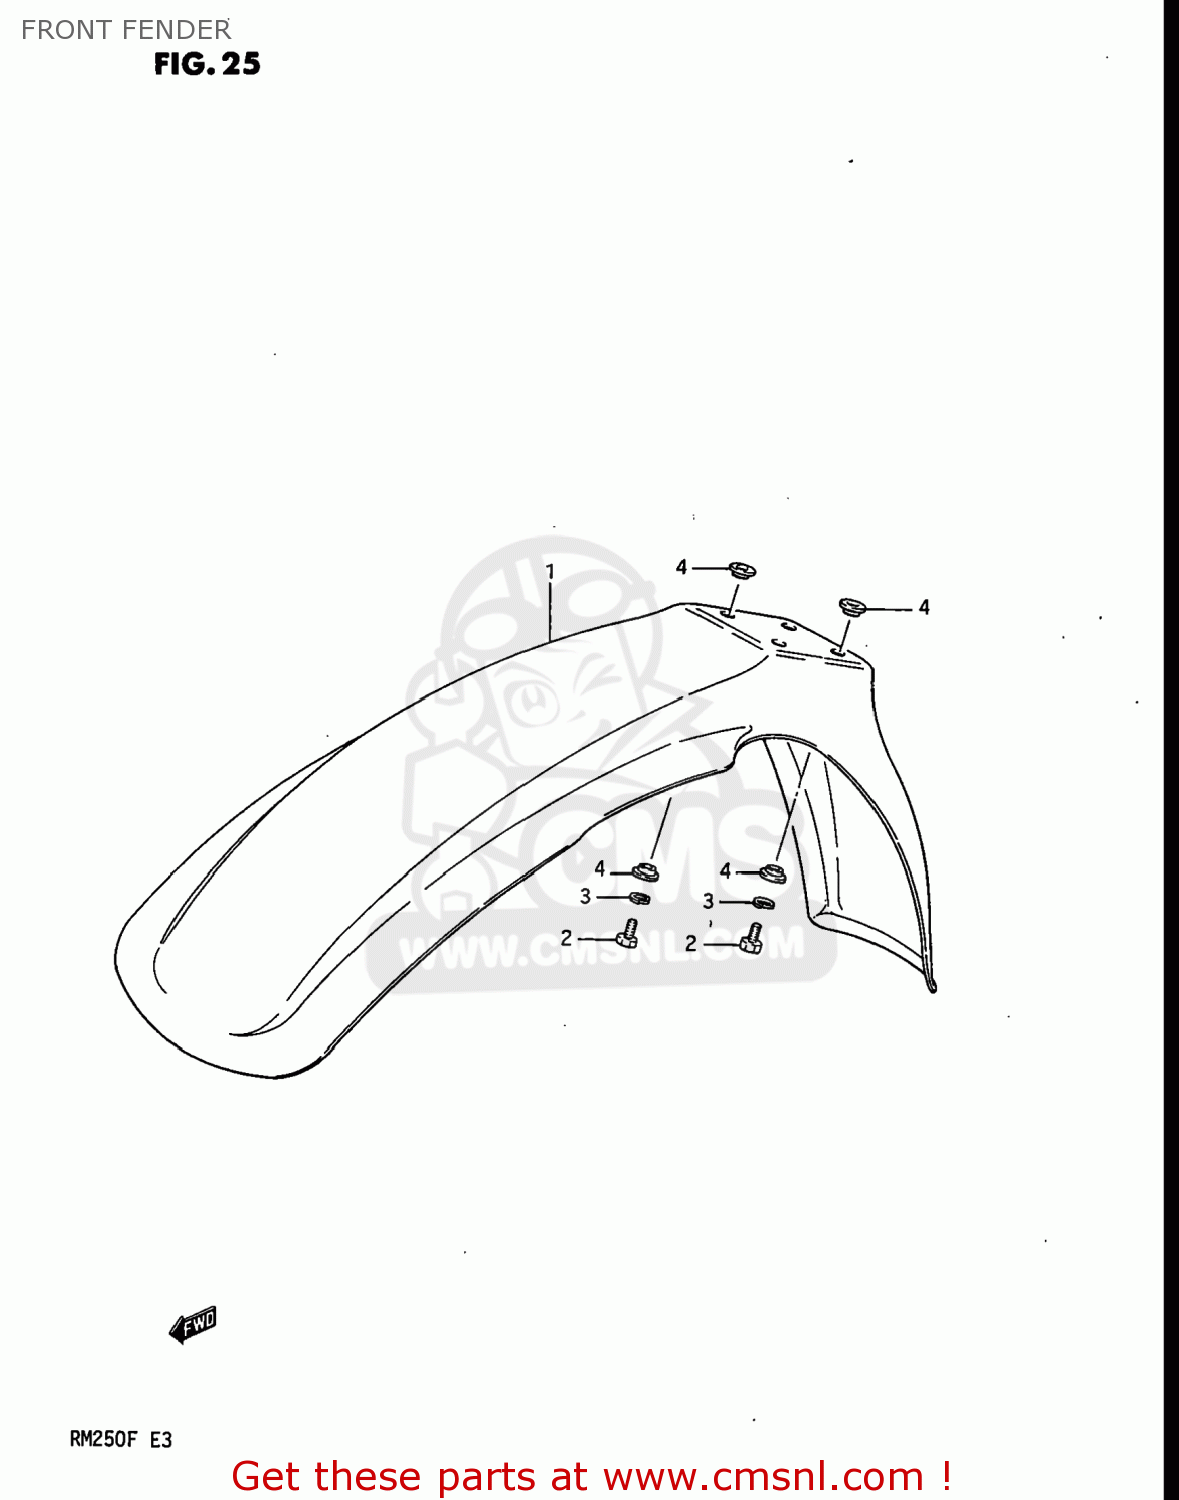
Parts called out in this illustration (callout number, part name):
1	FENDER,FRONT
2	BOLT, UPPER
3	LOCK WASHER
4	SPACER
